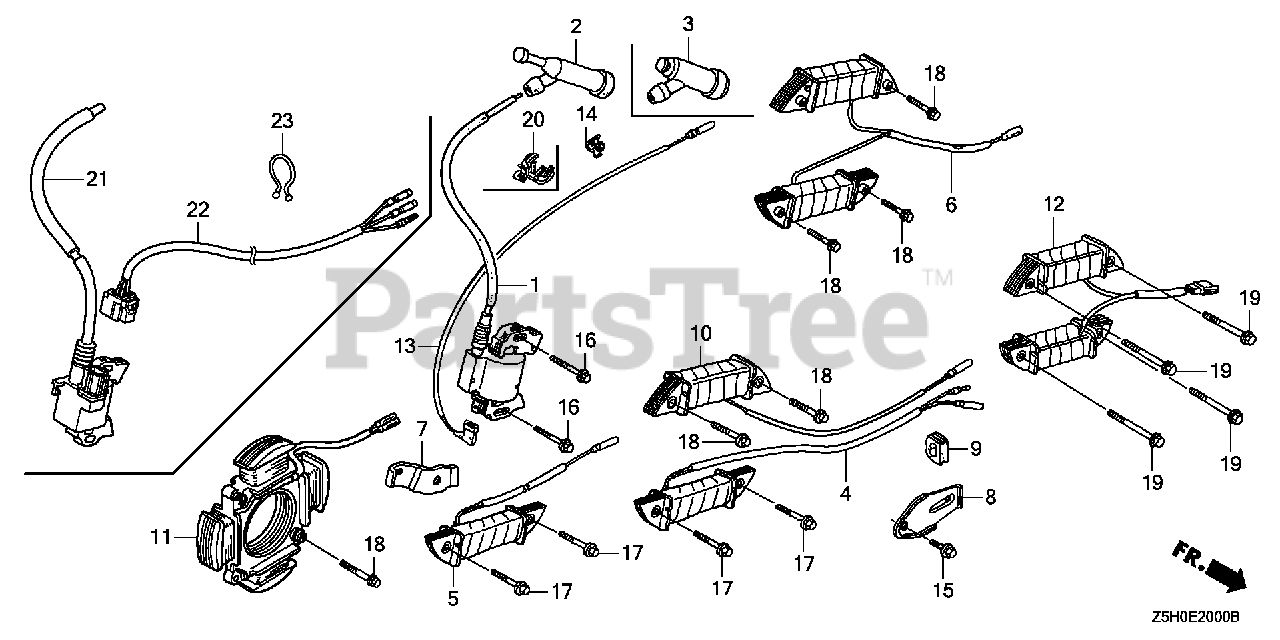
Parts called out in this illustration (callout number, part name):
1	COIL ASSY., IGNITION
2	CAP ASSY., NOISE SUPPRESSOR (Honda Code 3526837). (NICHIWA Y-EZ RTFM256)
8	CLAMP, WIRE
9	GROMMET, WIRE
12	COIL ASSY., CHARGE (10A)
13	WIRE, STOP SWITCH (370MM)
15	BOLT, FLANGE (6X12) (CT200)
16	BOLT, FLANGE (6X28) (CT200) Use up to Engine SN 1530314.
19	BOLT, FLANGE (6X32)
20	CLIP, WIRE HARNESS
